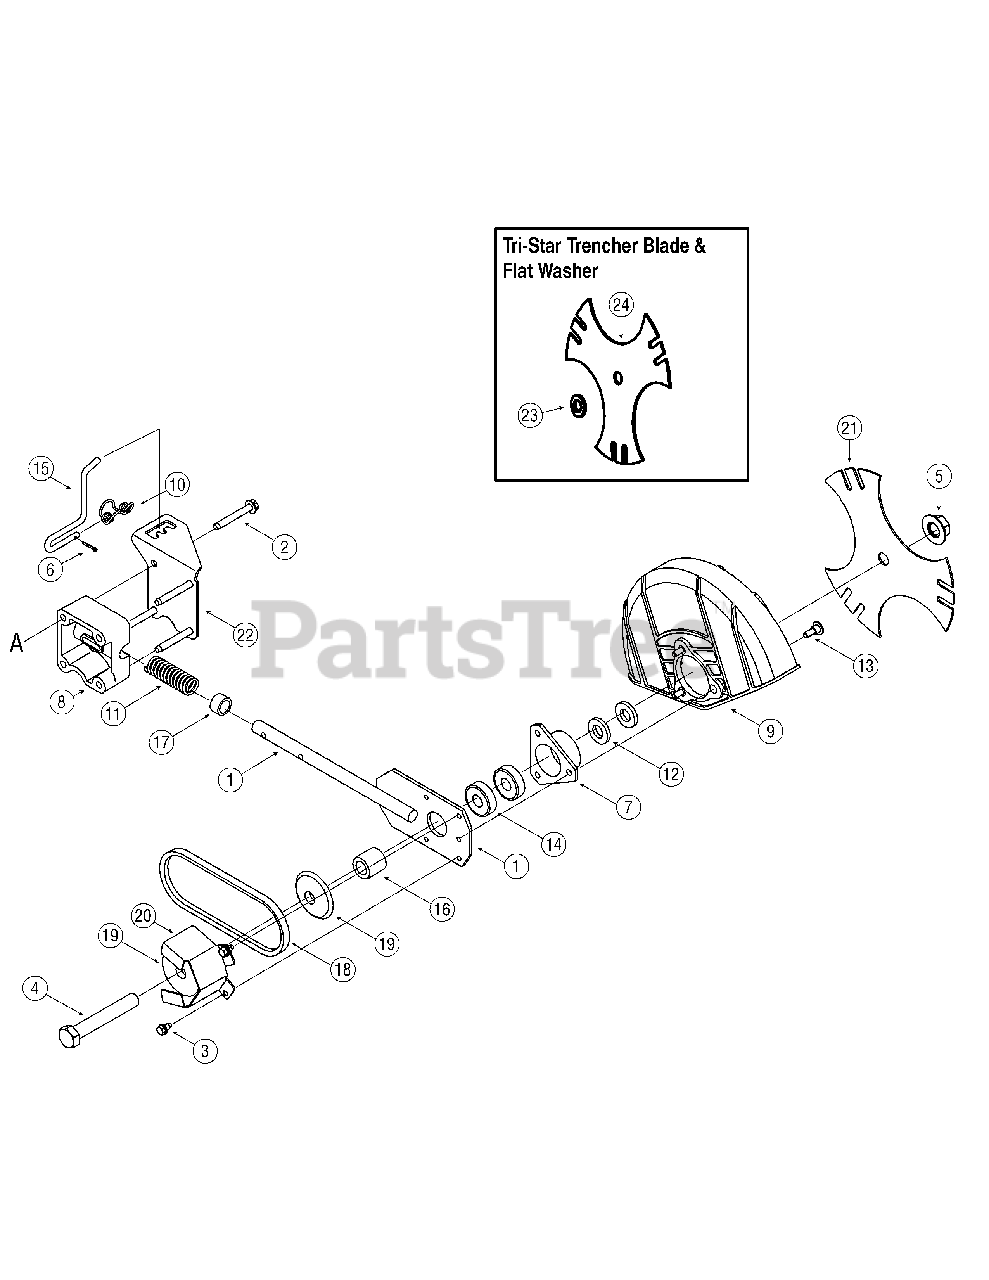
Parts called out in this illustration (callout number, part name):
1	Blade Plate Assembly
2	Hex Screw, 5/16-18
3	Self-tapping Screw, 1/4-20
4	Hex Screw, 5/8-18
5	Flange Nut, 5/8-18
6	Clevis Pin 3/32 x .625
7	Bearing Cup
8	Bearing Block
9	Blade Guard
10	Double Torsion Spring
11	Compression Spring
12	Flat Washer .635 x 1.24 x .181
13	Shoulder Screw
14	Bearing, .625 ID x 1.57 OD
15	Blade Adjustment Rod
16	Spacer, .63 x 1.12 x 1.06
17	Spacer, .64 x.88 x .50
18	Belt
19	Sheave
23	Flat Washer
